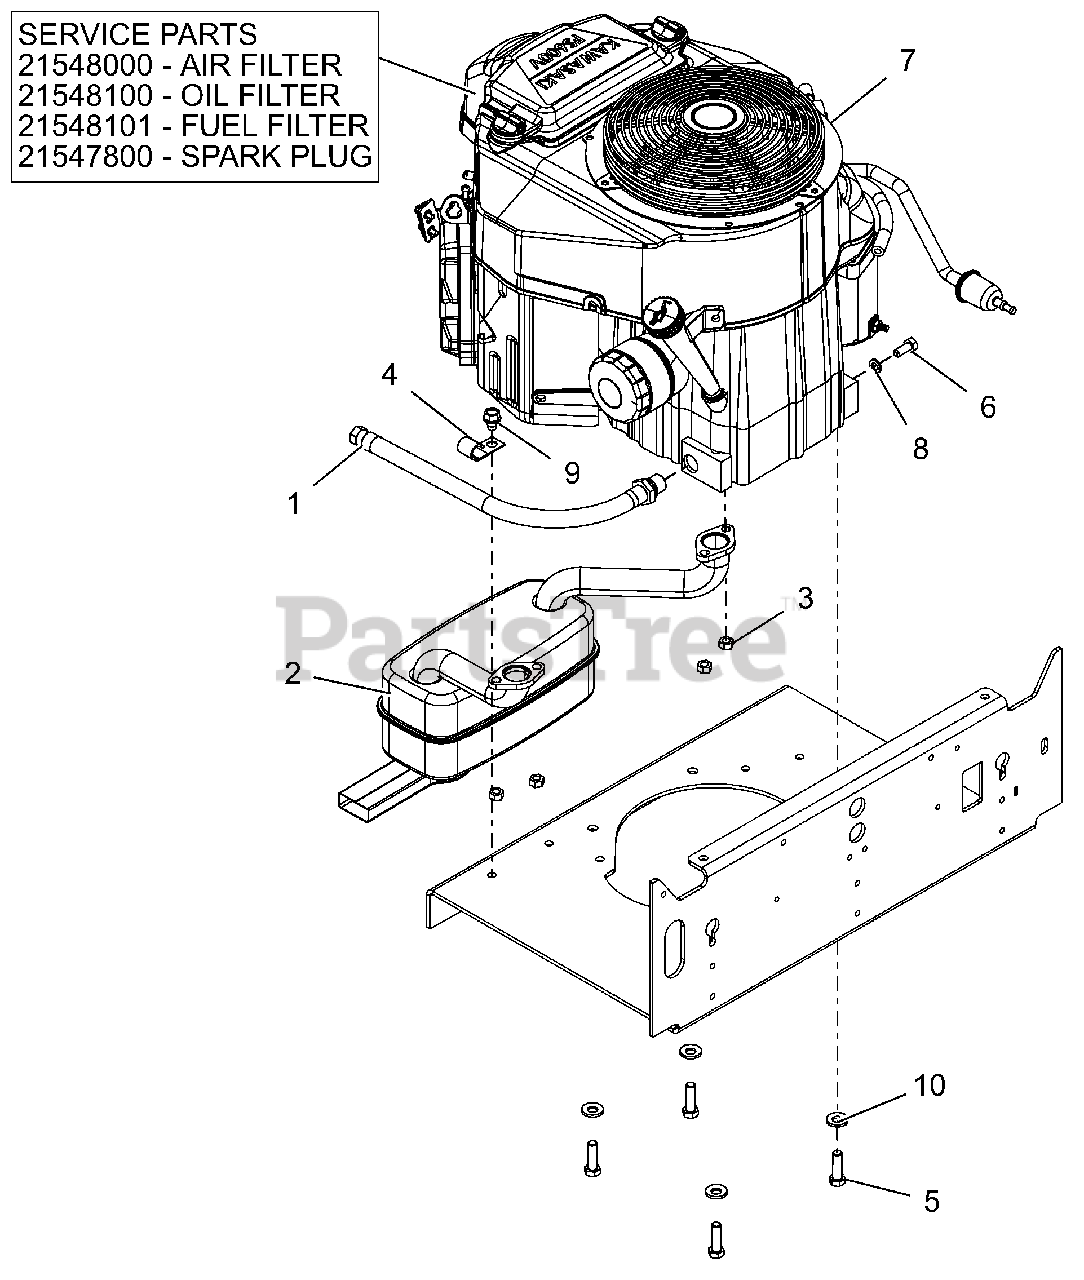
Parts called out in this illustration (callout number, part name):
1	HOSE, OIL DRAIN
2	MUFFLER, KAW FS691/730
3	NUT-LK-TOP M8-1.25 YWZC
5	BLT-HEX.38-16X1.25 G5YZ NYTORQ
6	@BLT-HEX M8-1.25X20 YWZC
7	ENGINE, KAWASAKI FS730
7	AIR FILTER, KAWASAKI FR
7	OIL FILTER, KAWASAKI FR
7	FUEL FILTER-KAWASAKI FR
7	SPARK PLUG, KAWASAKI FR
8	@WSHR-LK .31X.078 REG YWZC
9	@SCR-TAP .38-16X.50 HWH TR YWZ
10	WASHER, 3/8" SPRING DISC
